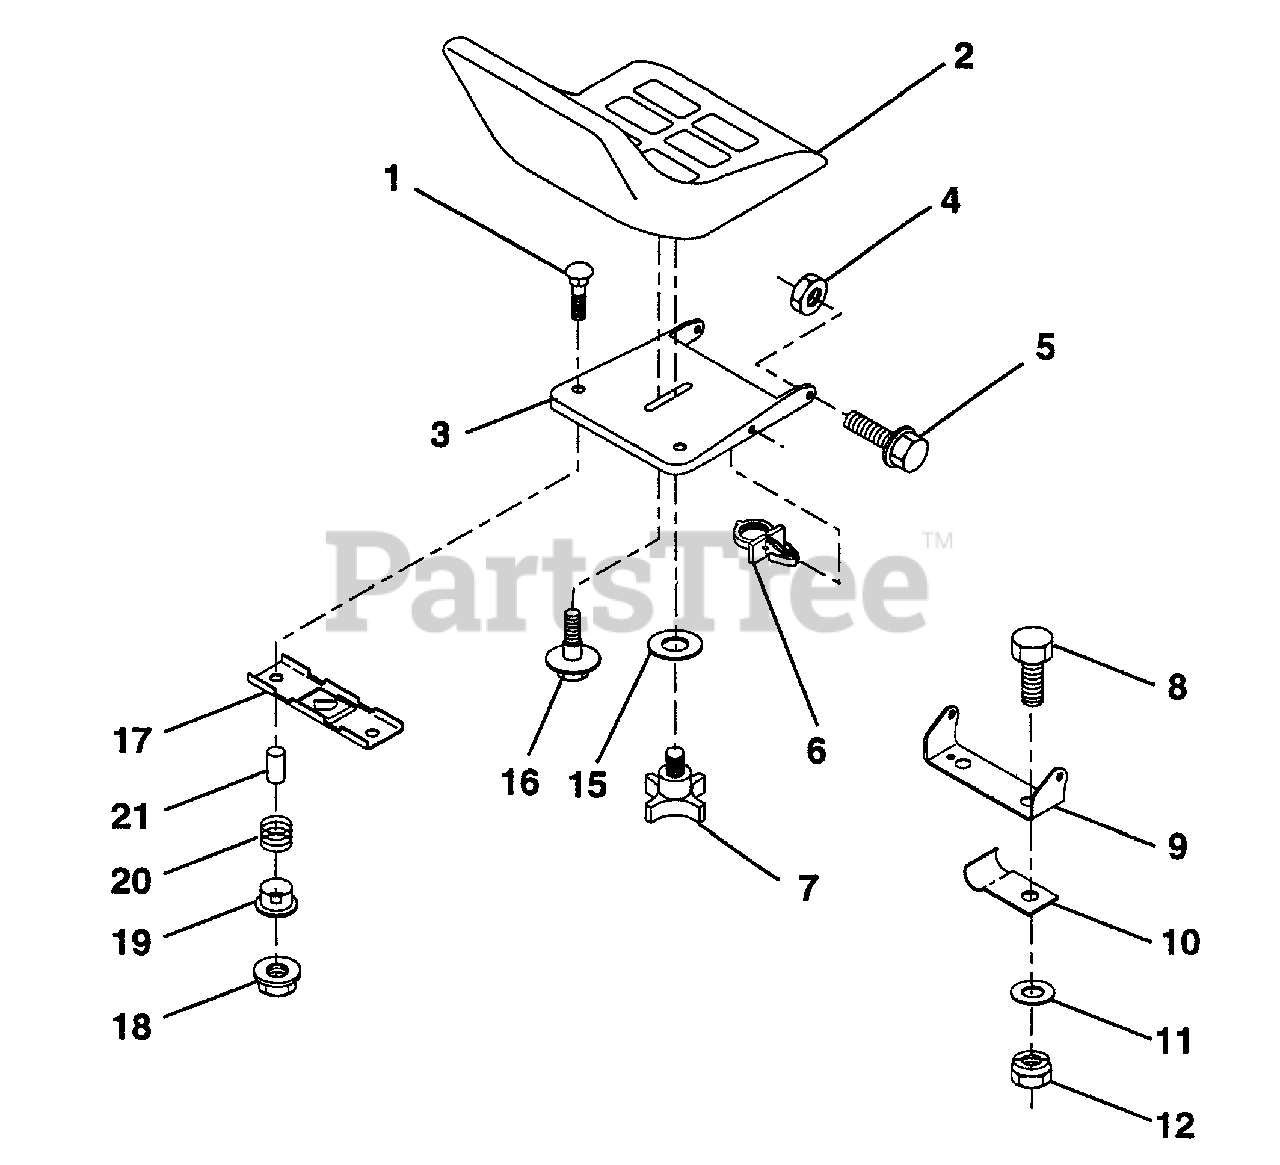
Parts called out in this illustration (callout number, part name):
1	Bolt, Carriage 1/4-20 x 1-3/8
2	Seat
3	Pan, Seat
4	Nut, Hex, Crownlock 5/16-18
5	Bolt, Shoulder 5/16-18 UNC
6	Clip, Insulated
7	Knob, Seat
8	Bolt, Hex, Fin. 3/8-16
9	Bracket, Pivot, Seat
11	Washer 12132 x 2 x 10 Gauge
12	Nut, Hex, Crownlock 3/8-16 UNC
15	Washer 17/32 x 1-3/16 x 12 Gauge
16	Bolt, Shoulder
17	Bracket, Switch Mounting
18	Nut, Hex, Large, Flange Lock
19	Bushing, Snap
20	Spring, Compression
21	Spacer, Split, Large .28 Id. x .96
